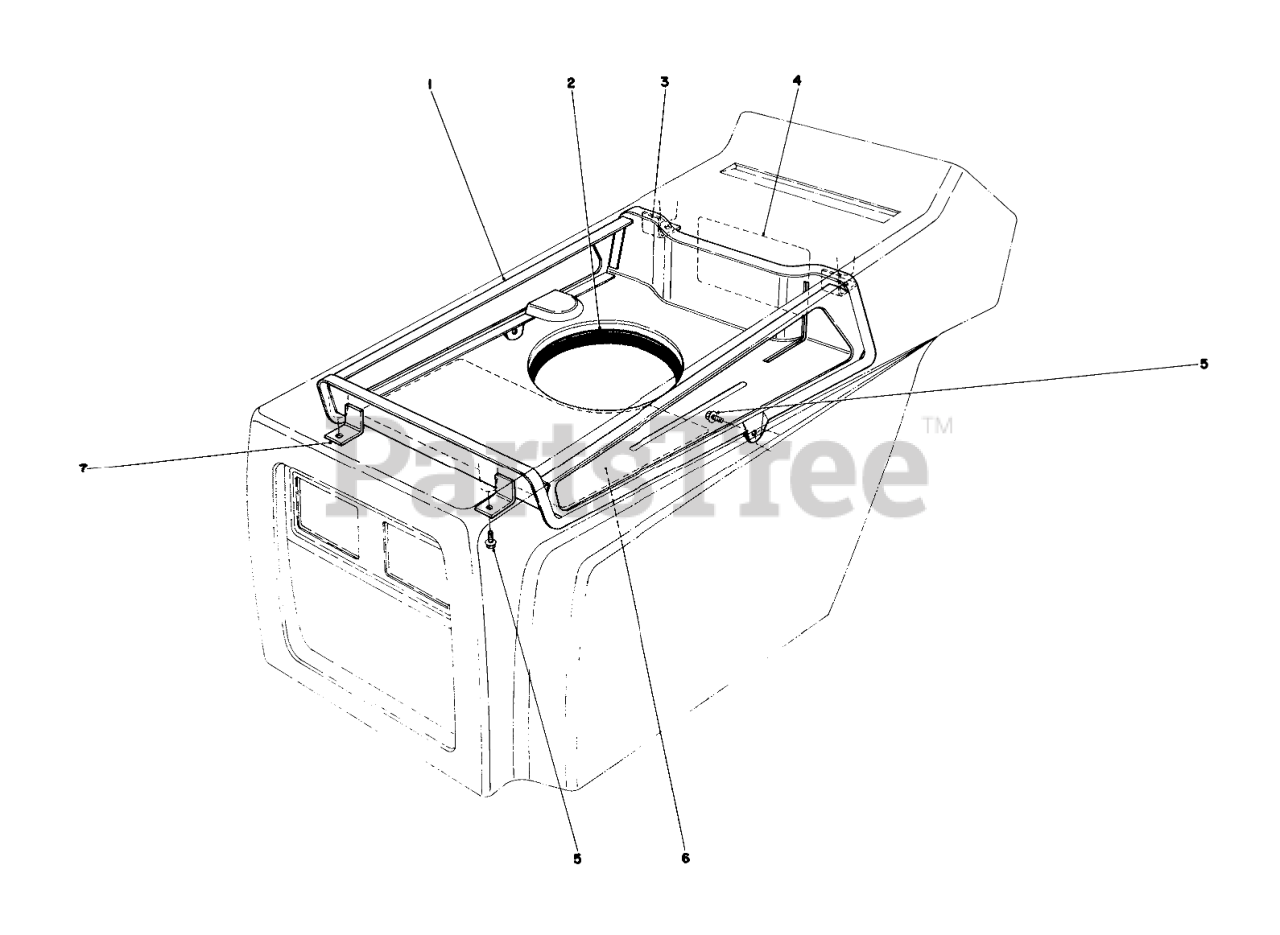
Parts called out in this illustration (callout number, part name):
1	Duct Hood
2	Seal Engine
4	Decal-Belt Change
5	SCREW-HWHTF
6	Decal Service
7	Bracket Duct Support
